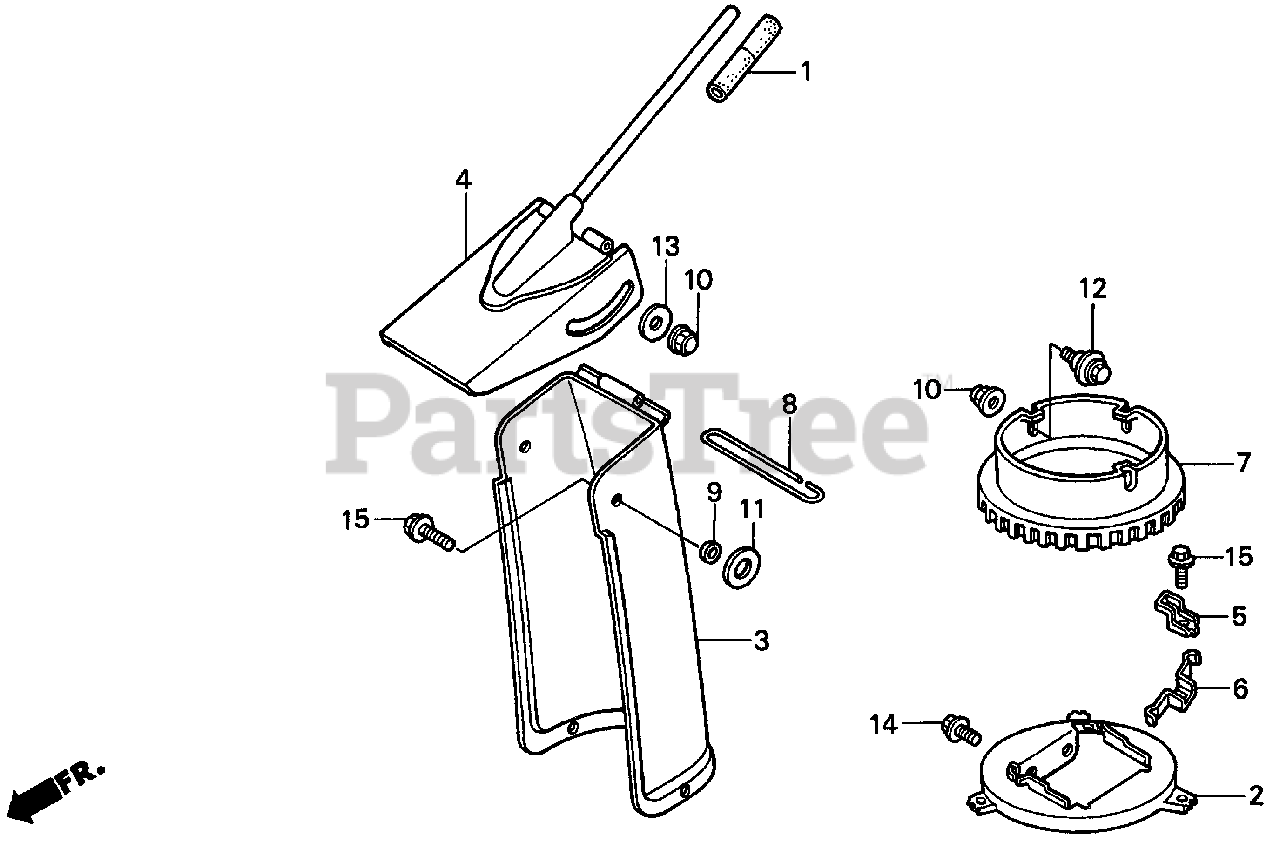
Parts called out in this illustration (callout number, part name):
1	GRIP, CHANGE LEVER
2	RECEIVER, CHUTE
3	CHUTE *R8* (BRIGHT RED)
4	GUIDE, CHUTE
5	PLATE, CHUTE SETTING
6	SPRING, CHUTE SETTING
7	BUSH, CHUTE
8	PIN, CHUTE GUIDE
9	COLLAR, CHUTE GUIDE
10	NUT, CAP (6MM)
11	SPRING, LEVER
12	BOLT, BUMPER (GREEN)
13	WASHER, PLAIN (6MM)
14	BOLT, FLANGE (6X10)
15	BOLT, FLANGE (6X14)
